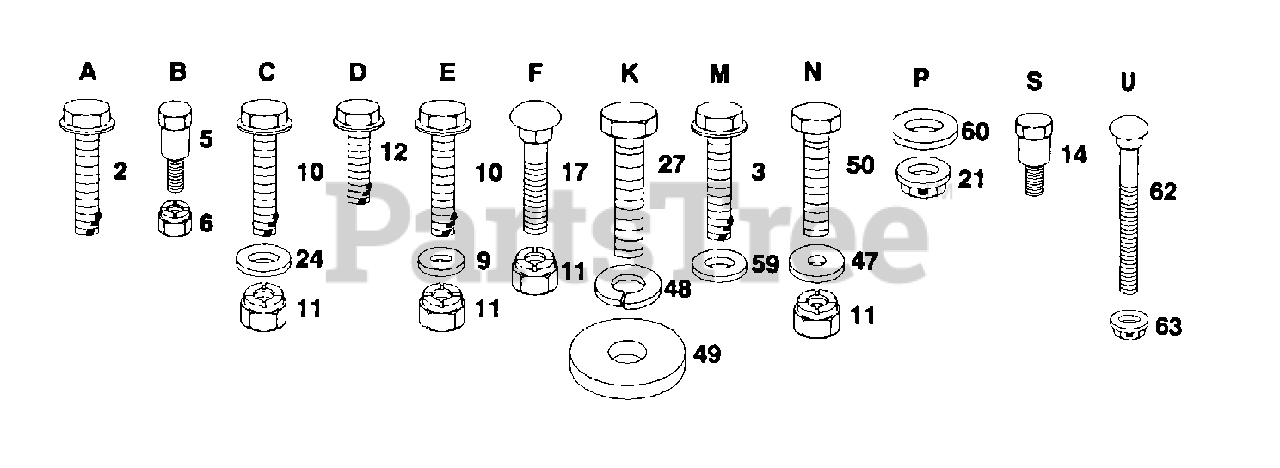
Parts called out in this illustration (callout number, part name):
2	SCREW
3	SCREW GTV
9	WASHER
12	SCREW LT
14	"BOLT,SHOULDER"
17	BOLT
21	PAL NUT LT
24	WASHER
27	BOLT
50	BOLT
59	WASHER
60	WASHER PM
62	BOLT
